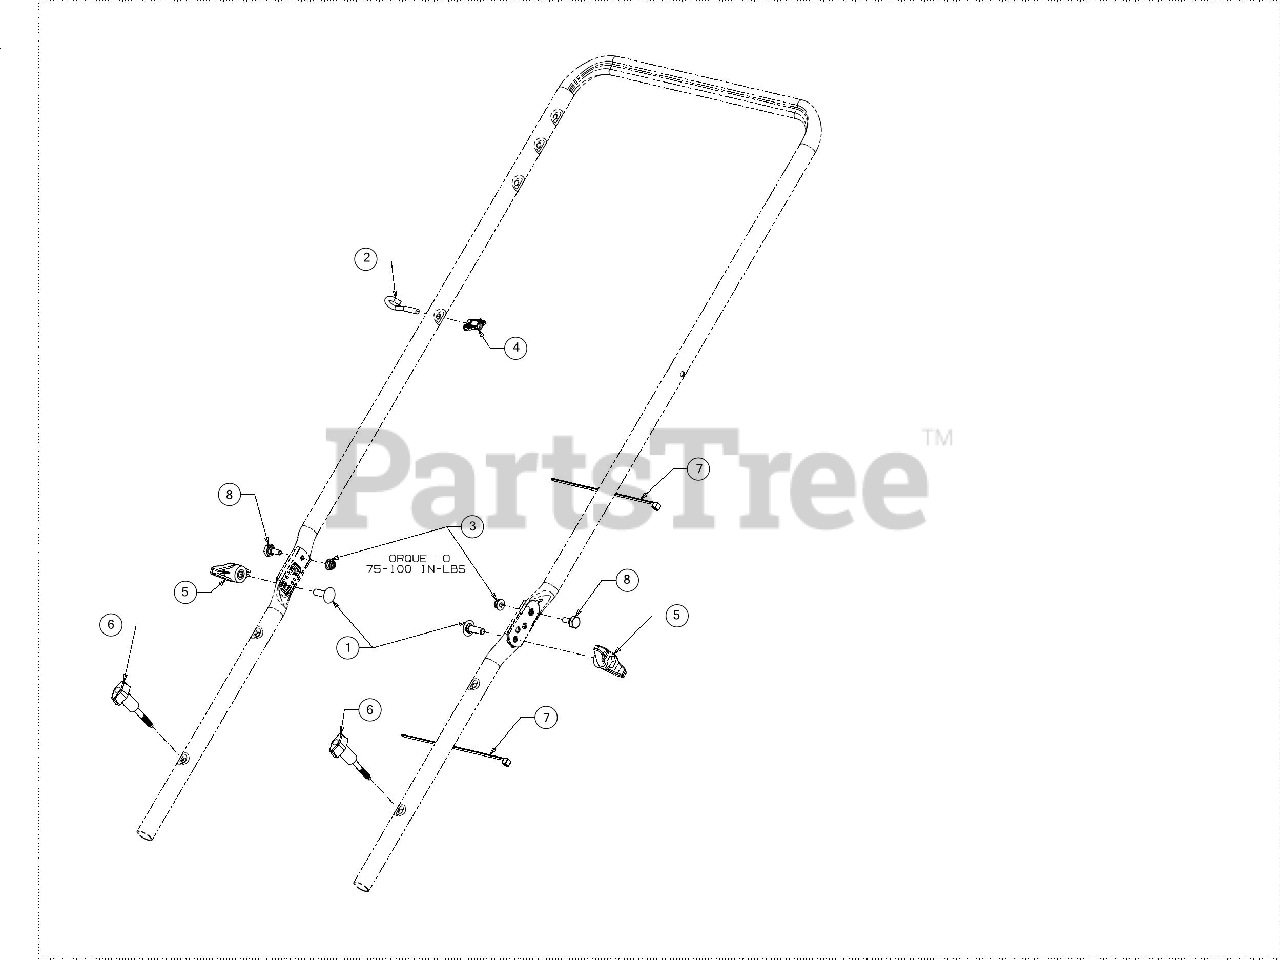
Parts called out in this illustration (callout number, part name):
1	SCREW 5/16-18 X 1.00 GR5
2	EYEBOLT 1/4-20
3	FLANGE LOCK NUT
4	HANDLE KNOB
5	WING KNOB 5/16-18
6	WING KNOB 1/4-20
7	CABLE TIE 7"
8	SHOULDER SCREW
